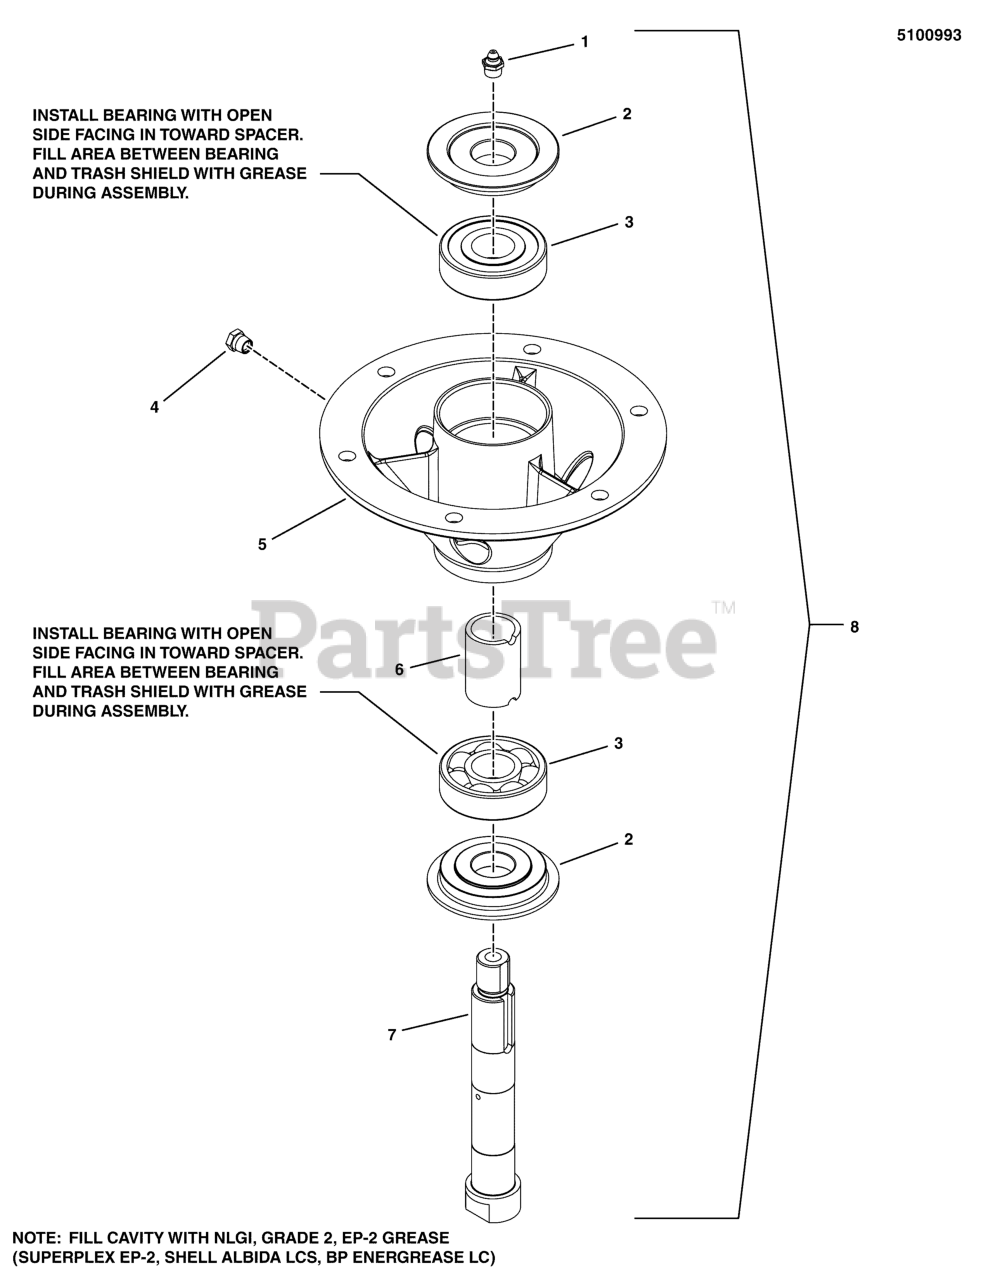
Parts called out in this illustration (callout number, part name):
1	FITTING
2	TRASH SHIELD
3	BEARING, .98 X 2.44 X .67
4	FITTING, RELIEF, 1-5 PSI
5	HOUSING, SPINDLE, BOTTOM MOUNT SM
6	SPACER, 1.00 X 1.25 X 1.75
7	SPINDLE SHAFT
8	SPINDLE ASSM, CAST IRON 8.0 - 6-BOLT
